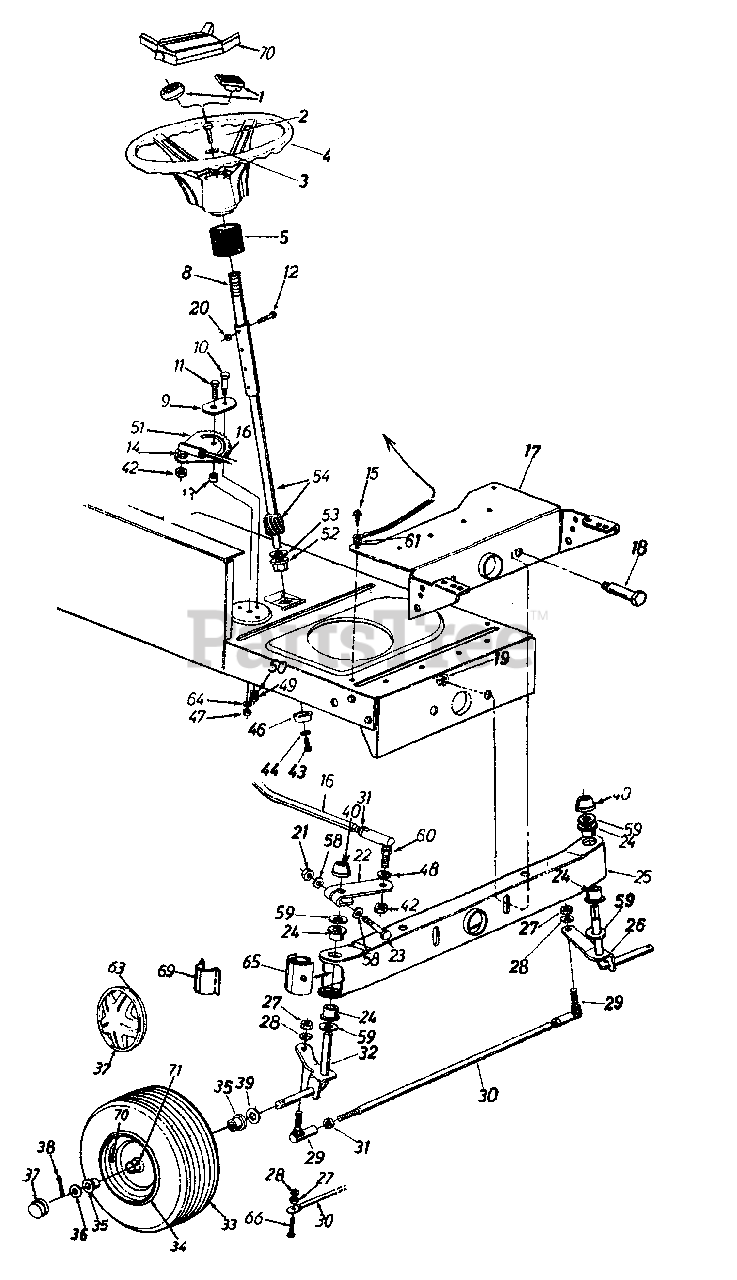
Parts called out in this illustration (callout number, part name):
1	Steering Wheel Cap
2	Hex Bolt 5/16-18 x 1" Lg.
3	Belleville Wash. .345" I.D.
4	Steering Wheel (3 Spoke)
5	Steering Bellow-4.5"
8	Upper Steering Shaft
9	Retainer Plate
10	Shoulder Bolt .437" Dia. x .35 Lg. 5/16-18 Thd.
11	Hex Bolt 3/8-24 x 1.0" Lg. (Gr. 5)
12	Hex Bolt 1/4-20 x 1.25" Lg.
13	Spacer .380" I.D. x .625" O.D. x .227
14	L-Wash. 3/8" I.D. (H.D.)
15	Hex Wash. Hd. Self-Tap Scr.
16	Steering Drag Link
18	Shoulder Bolt .498" Dia. x 2.04 Lg. 3/8-16 Thd.
19	Flanged L- Nut 3/8-16 Thd.
20	Hex L-Nut 3/8-24 Thd.
21	Hex L-Nut 5/16-24 Thd.
22	Steering Arm Front Axle
23	Hex Bolt 5/16-24 x 2.00" Lg. (Gr.5)
24	Hex Flg. Brg. .632 I.D.
26	Front Axle Ass'y.-L.H. 15" x 6" Round Shoulder
27	Hex Nut 3/8-24 Thd.
28	L-Wash. 3/8" I.D.
29	Ball Joint 3/8-24 Thd.
30	Tie Rod (Adjustable)
31	Hex Jam Nut 3/8-24 Thd.
32	Front Axle Ass'y.-R.H. 15" x 6" Round Shoulder
36	FL-Wash. .635 I.D. x 1.59" O.D.
37	Front Wheel Hub Cap
38	Cotter Pin 1/8" Dia. x 1.25"
39	FL-Wash. .640" I.D. x 1.24" O.D.
40	Push Cap 5/8" Dia. Rod
42	Hex Jam Nut 3/8-24 Thd.
43	Hex Patch Bolt 5/16-18 x .62"
44	L-Wash. 5/16" I.D.
46	Cap
47	Hex Cent. L-Nut 3/8-24 Thd.
48	L-Wash. 3/8" I.D.
49	Hex Cent. L-Nut 5/16-18 Thd.
50	L-Wash. 5/16" I.D.
51	Steering Gear Segment
52	Hex Flg. Brg. .634 I.D.
53	FL-Wash. (Hardened)
54	Lower Steering Shaft
58	Wave-Wash. .32" I.D. x .62" O.D.
59	FL-Wash. (Hardened)
60	Drag Link Ball Joint 3/8-24 Thd.
61	Ext. L-Wash. 5/16" I.D.
63	Spring Clip
64	Bell-Wash. .39" I.D. x 1.38" O.D.
65	Pivot Bar End Cap
66	Hex Bolt 3/8-24 x 1.5" Lg. (Gr. 5)
69	Axle Cap
70	Steering Wheel Insert
